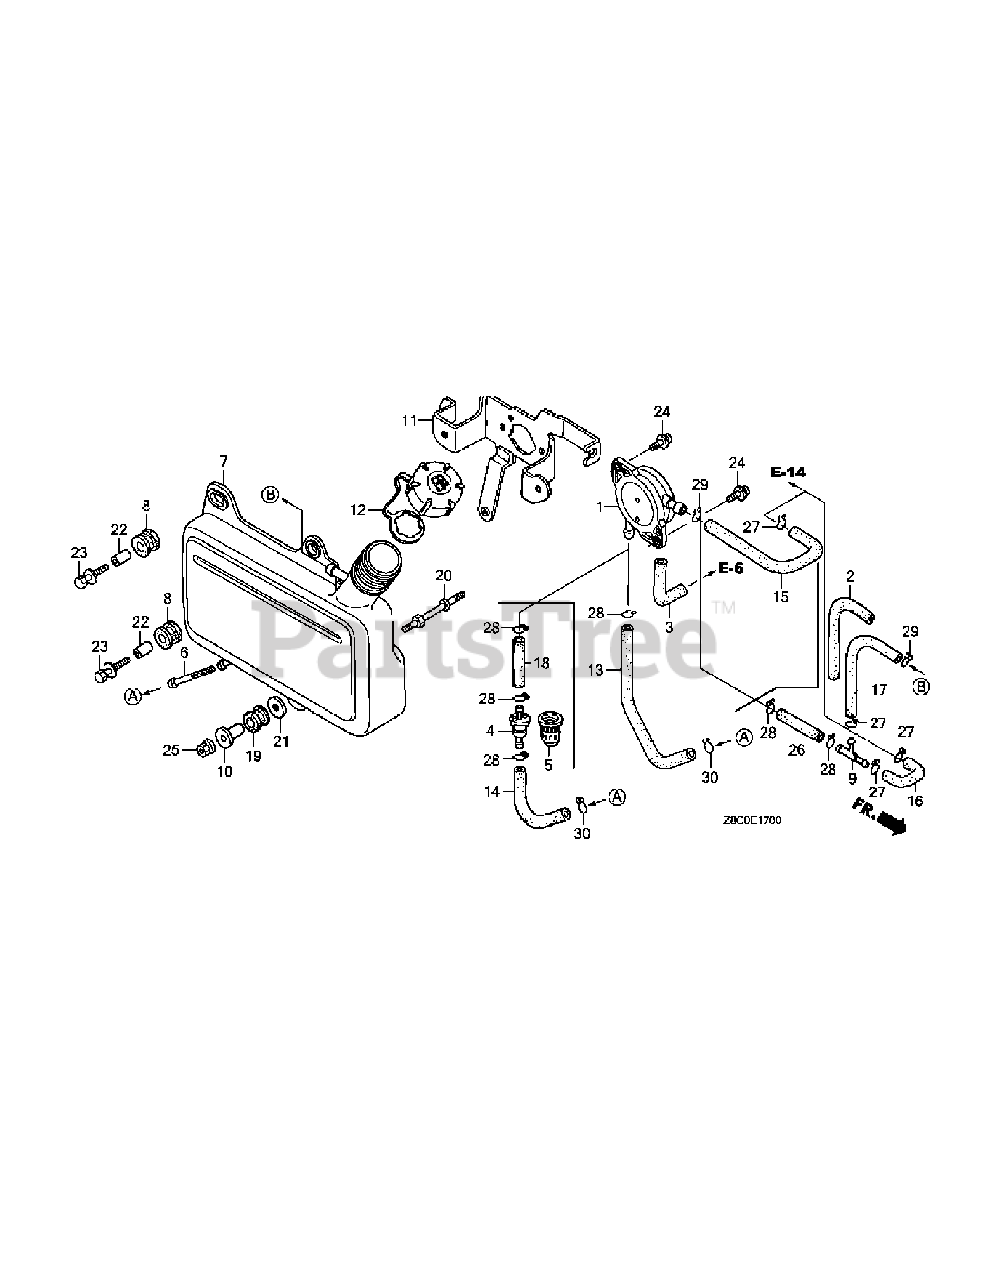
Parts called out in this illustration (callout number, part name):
1	Pump Assy., Fuel
2	Rubber, Supporter (107Mm)
3	Tube, Diaphragm
4	Fuel Filter
5	Suspension, Strainer
7	Tank, Fuel
8	Rubber B, Tank Mounting
9	Joint, Fuel Tube
10	Collar, Fr. Cover Setting
11	Stay A, Fuel Tank
12	Cap Assy., Fuel Tank
13	Not used in this application
14	Tube, Fuel Tank
15	Not used in this application
16	Tube, Fuel
17	Tube, Fuel Return
18	Tube, Fuel Pump
19	Cushion, Rr. Fender
20	Bolt, Fuel Tank Stud (H=30Mm)
21	Washer, 6Mm
22	Collar, 14X6.1
23	Bolt-Washer, 6X25
24	Screw-Washer, 5X14
25	Nut, Flange, 6Mm
26	Tube, Fuel, 5.3X33
27	Clip, Tube (B8)
28	Clip, Tube (B10)
29	Clip, Tube (C9)
30	Clip, Tube (C11)
